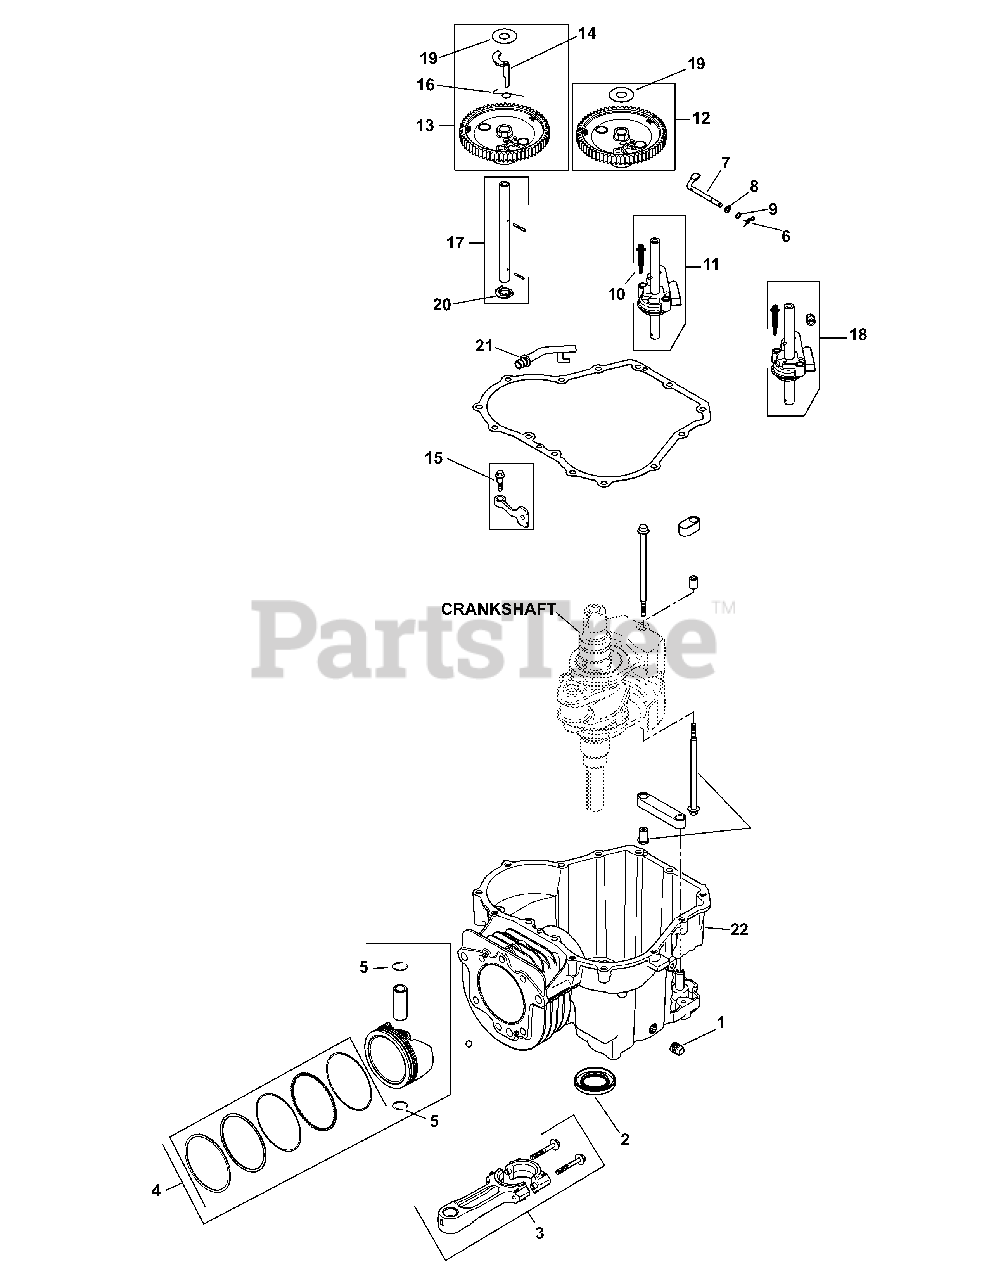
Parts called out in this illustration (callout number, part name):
1	Square Head Pipe Plug, 3/8
3	Connecting Assembly Rod
4	Piston W/ Ring Set Kit, 94mm
5	Piston Pin Retainer
6	Hitch Pin Clip
7	Governor Cross Shaft
8	Flat Washer, 6 Mm
9	Flat Washer, 1/4
10	Shd. Thd. Frm. Screw
11	Oil Pump Assembly Kit
12	Cam Lobe Assembly
13	Cam Gear Assembly
14	Acr. Weight & Follower Kit
15	Shd. Thd. Frm. Screw, M6 x 1 x 26
17	Cam Center Shaft Kit
18	Oil Pump Kit (Shallow 10mm)
19	Thrust -Acr. Washer
20	Thrust Washer
21	Drainback Tube
22	Crankcase (Use: Short Block)
